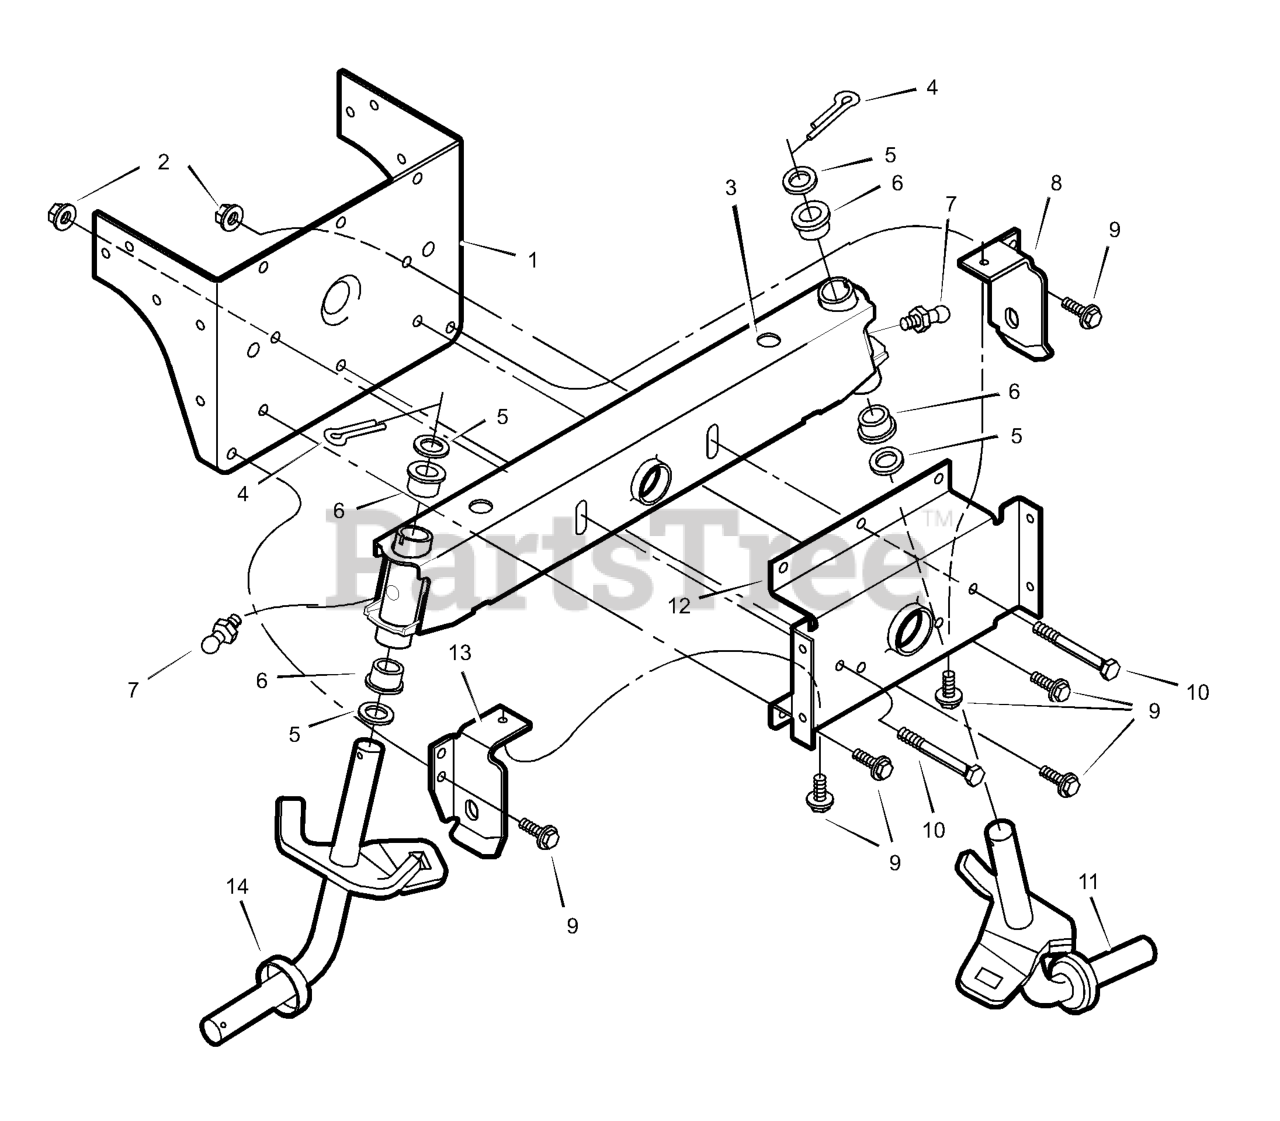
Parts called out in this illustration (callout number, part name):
1	Bracket, Rear Hanger
2	Nut, Flange
3	Axle Assembly
4	Pin, Hair
6	Bearing, Spindle
7	Fitting, Lub
8	Hanger, Left Deck
11	Spindle Assembly, Left
12	Hanger, Axle
13	Hanger, Right Deck
14	Spindle Assembly, Right
